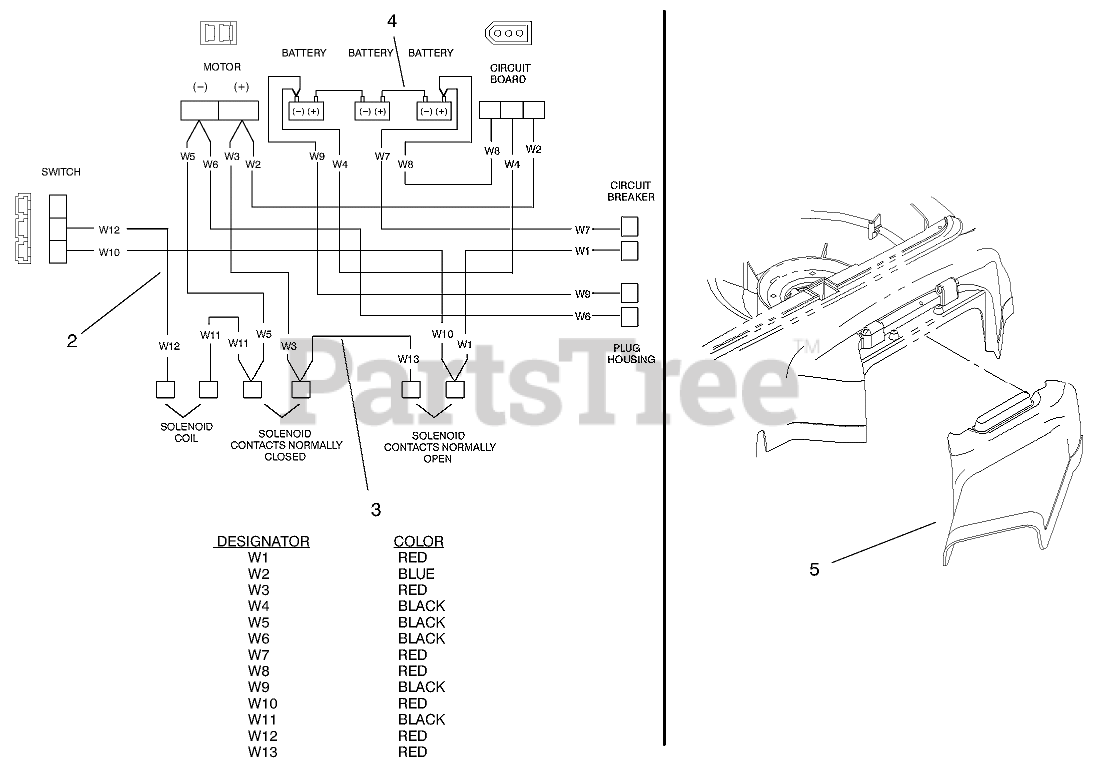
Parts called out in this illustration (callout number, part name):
2	HARNESS-WIRE 24 & 36 VOLT
3	HARNESS-WIRE JUMPER
4	HARNESS
5	CHUTE - SIDE
